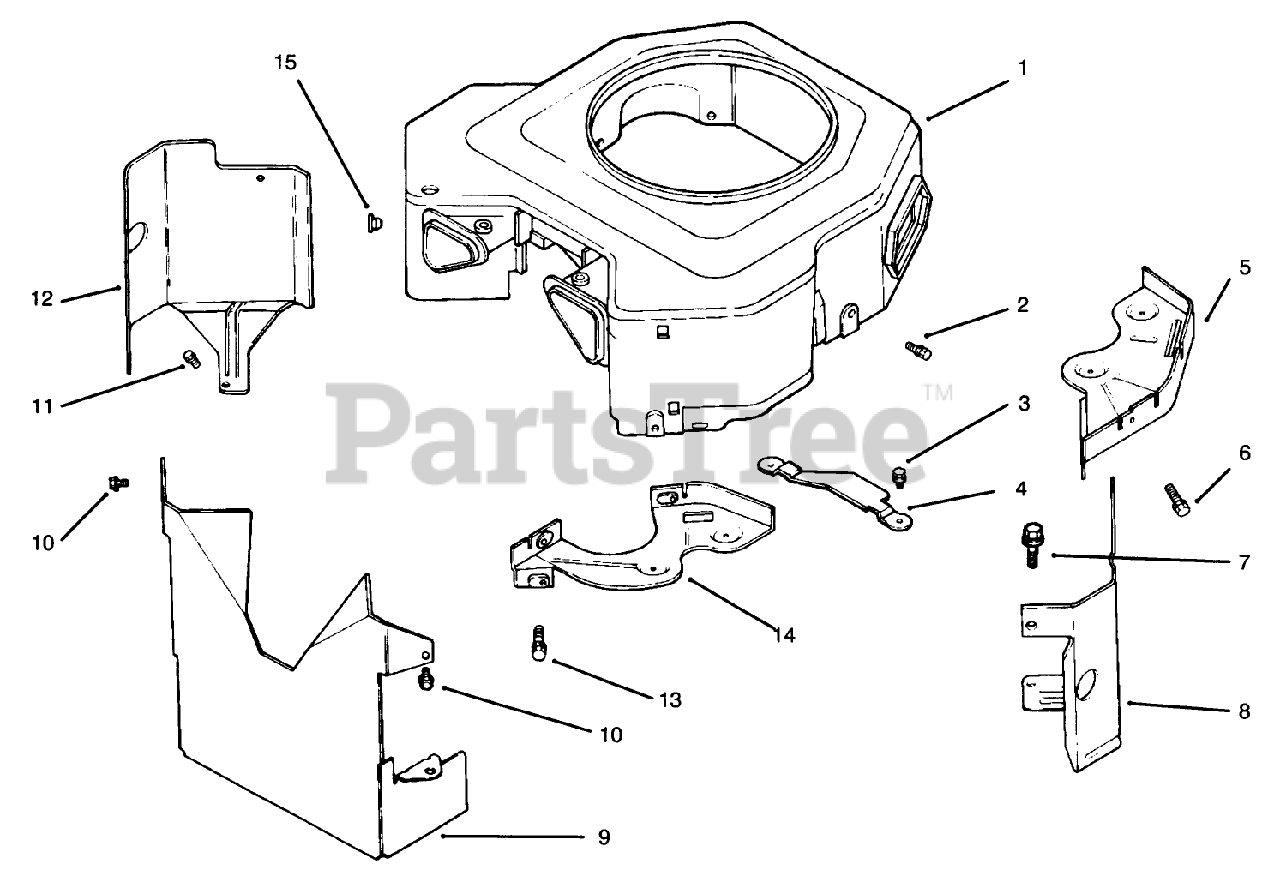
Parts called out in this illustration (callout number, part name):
1	Housing-Blower
2	Loose Parts Package
4	Guard-Flywheel (Only On: 72103, 72083)
5	Plate-Backing #2 side
8	Baffle Cylinder #2 Side
9	Baffle-Valley
12	Baffle-Cylinder #1 Side
13	Loose Parts Package
14	Plate-Backing #1
15	Nut INCL W/Blower Hsng (Only On: 72103)
